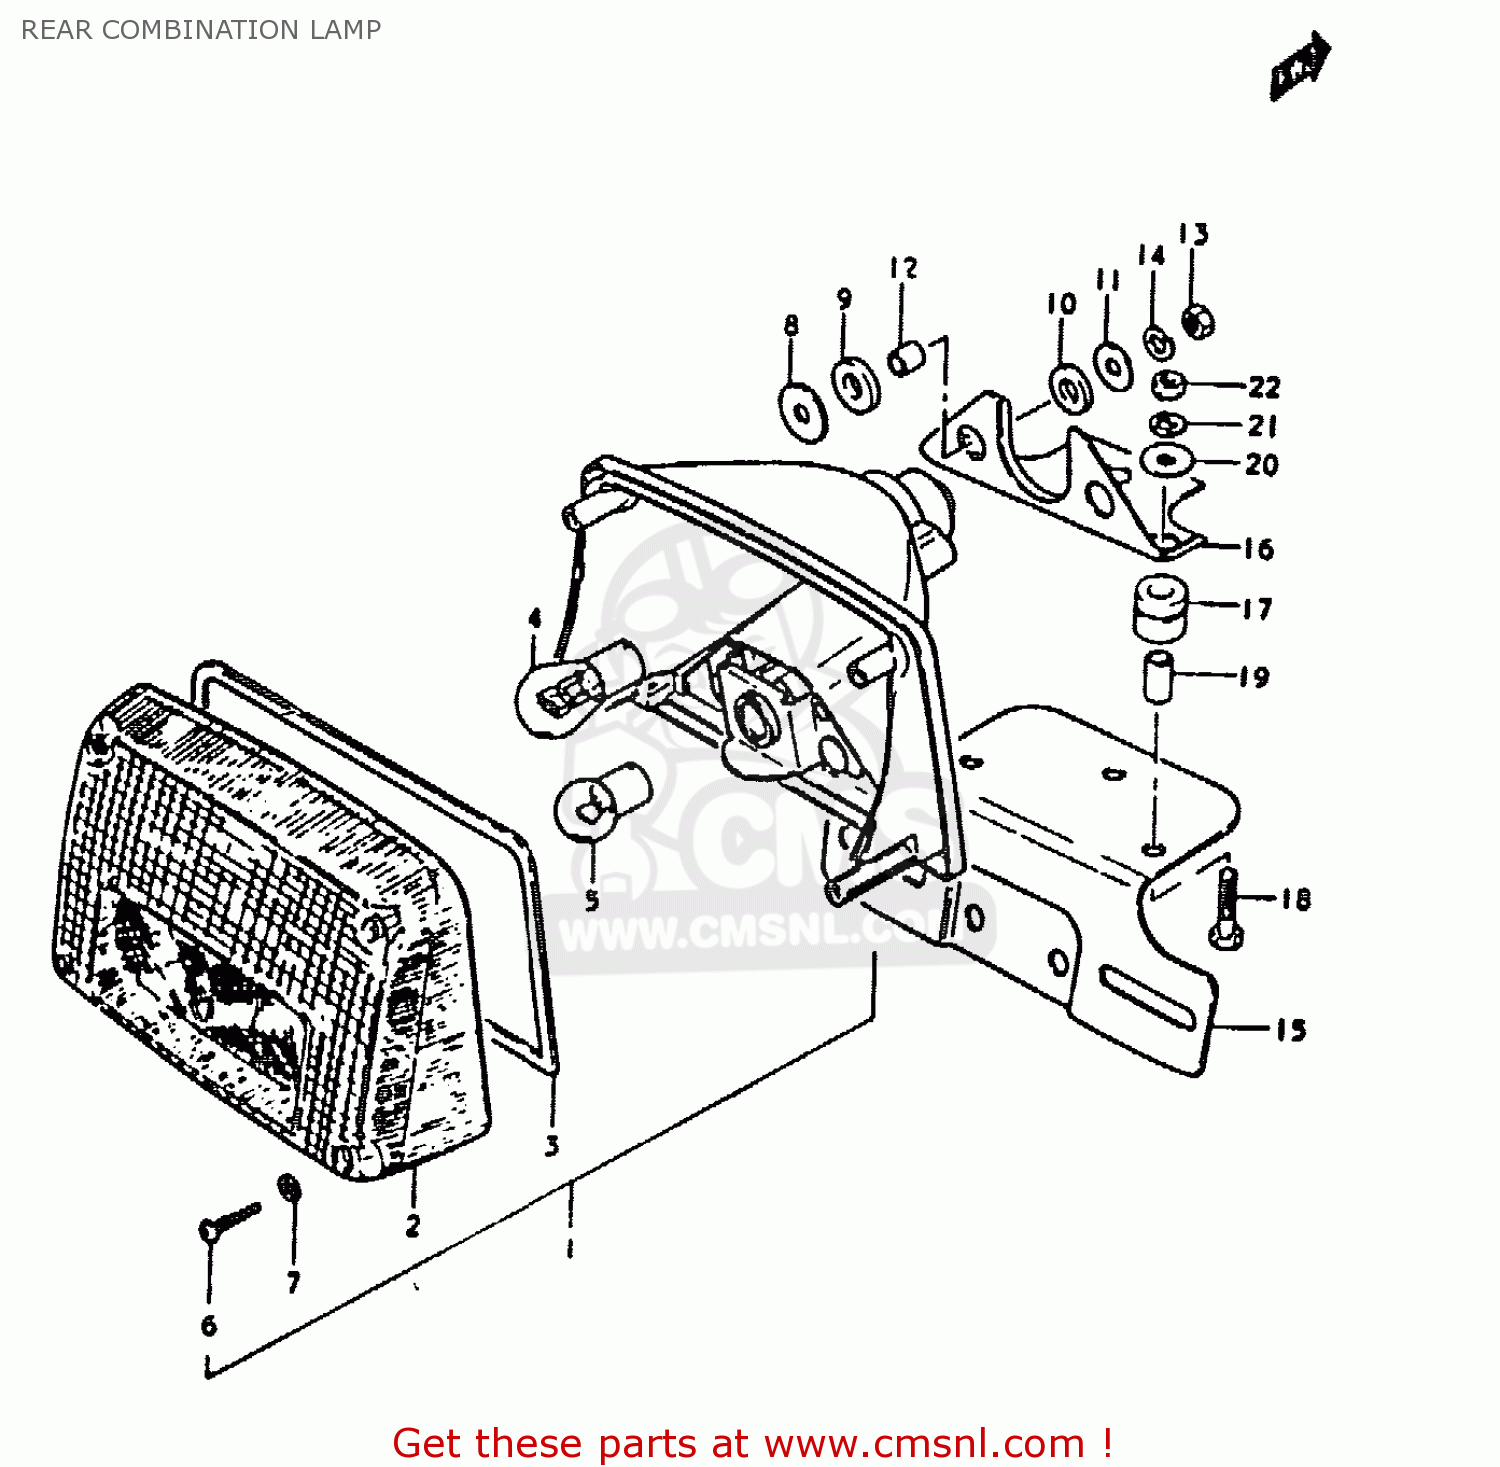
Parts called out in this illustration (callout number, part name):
1	LAMP ASSEMBLY,REAR COMBINATION
2	LENS,REAR COMBINATION LAMP
3	GASKET (NAS)
4	BULB(12V23W)
5	BULB
6	SCREW
7	GASKET (NAS)
8	WASHER
9	CUSHION
10	CUSHION
11	WASHER (6.5X24X1.6)
12	SPACER(6.1X9X7.5)
13	NUT
14	LOCK WASHER
15	PLATE, LICENSE
16	BRACKET,LICENSE PLATE
17	CUSHION, BRACKET
18	BOLT
19	SPACER (6.1X8X15.5)
20	WASHER
21	LOCK WASHER
22	NUT
